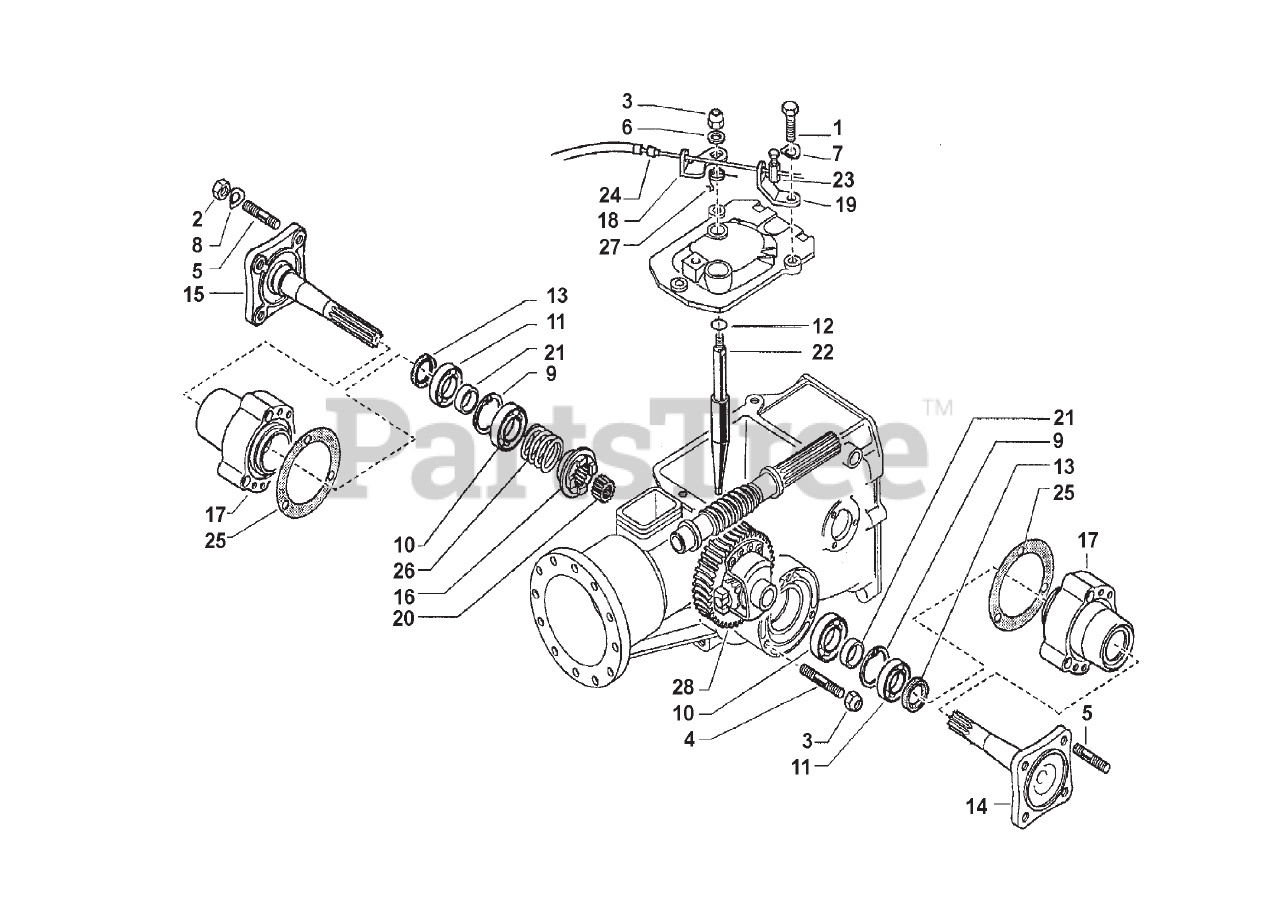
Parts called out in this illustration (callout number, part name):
1	BOLT M8X30
2	NUT M10
3	SELF LOCKING NUT M8
4	STUD M8X46
5	STUD M10X40
6	FLAT WASHER
7	LOCK WASHER
8	WASHER
9	INTERNAL SNAP RING D 47
10	BEARING 25X52X15
11	BEARING 25X47X12
12	O-RING
13	SEAL M30X40X7
14	HALF AXLE LH
15	HALF AXLE RH
16	COUPLING
17	HUB FOR HALF AXLE
18	RELEASE LEVER
19	CABLE BRACKET DIFFERENTIAL
20	DIFFERENTIAL SPACER
23	CABLE CLAMP
24	SHEATH ENDS
25	GASKET
26	SPRING
27	SPRING
28	DIFFERENTIAL COMPLETE
